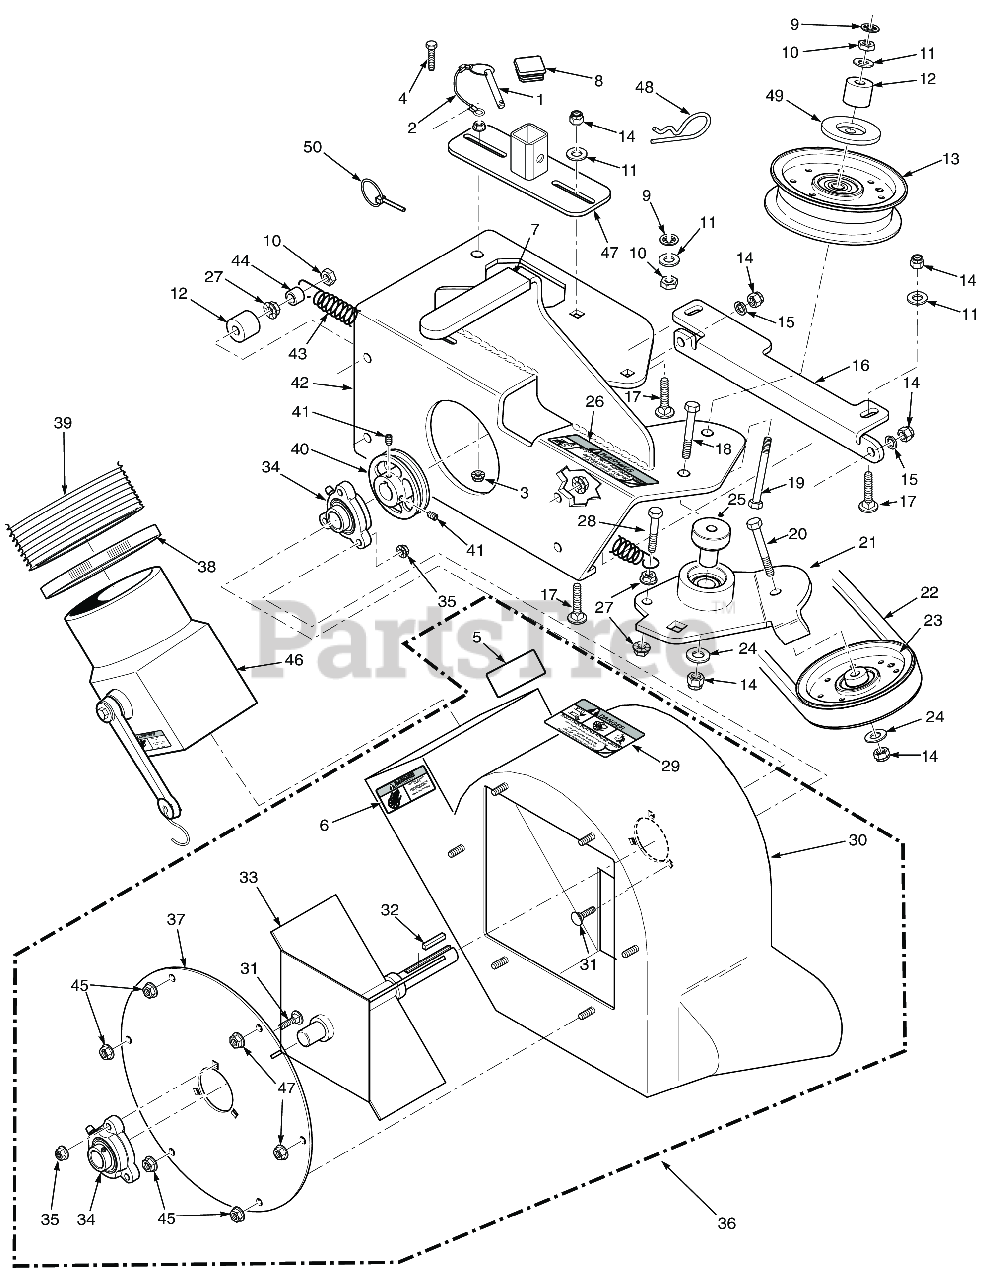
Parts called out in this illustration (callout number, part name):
1	Pin, Ring 1/2 x 2-1/4"
2	Lanyard, Deck Height Pin
3	NUT, 1/4-20 SERRATED FLANGE HEX HEAD
4	SERR. FLG. HEX HEAD CAPSCREW, 5/16-18 X 3/4
5	Decal, Blower
6	Decal, Rotating Blower
7	Grip, Deck Latch Lever
8	Cap, Square Vinyl
9	Nut, Push-On - 3/8" Dia.
10	Bolt, Hex Head 3/8-16 x 1" Ser. Flg.
11	Flatwasher, 3/8" Special (.391 x .938 x .105)
12	SPACER, J-PULL ROD
13	Pulley, Idler 3-1/2" Dia. - 52"
14	HEX NUT, ELASTIC STOP LOCK, 3/8-16
15	Lockwasher, 3/8" Spring, Kawasaki FX / FS
16	Plate, Catcher Mounting
17	Bolt, RDHD Carr. 3/8-16 x 1-1/2 (52" & 61")
18	Bolt, Hex Head 3/8-16 x 3" - 52"
19	Bolt, Hex Head 3/8-16 x 3-1/2" Full Thread
20	Bolt, Hex Head 3/8-16 x 1-3/4" (Kohler EFI)
21	Idler Arm Assembly - 52"
22	Belt, GC-SCZ-48V / STCII-48V
23	Pulley, 3-1/2" O.D., GC-STT 52"
24	Flatwasher, 3/8 (.391 x .938 x .105 HD) Grade 8
25	Pivot, Idler Long - 52"
26	Decal, Warning - Belt Cover
27	NUT, 3/8-16 SERRATED FLANGE HEX HEAD
28	Bolt, Hex Head 3/8-16 x 1-1/2" Grade 8 Black
29	Decal, Danger
30	Blower Housing Weldment w/Decals
31	Bolt, 5/16-18 x .75 RHSN Carriage
32	KEY 1/4 X 1/4 X 1 1/2"(FOR 1" CRANKSHAFT
33	Fan Weldment
34	Bearing Assembly
35	HEX NUT, ELASTIC STOP LOCK, 5/16-18
36	Blower Housing Assembly, GC-STT
37	COVER, BLOWER HOUSING
38	Clamp, 8-5/8" Max Dia. (61")
39	Hose, 8.00" Dia. x 68" Long
40	Pulley, 4-3/4" O.D. - 1" Bore
41	Setscrew, Hex Socket Knurl Cup Pt. 5/16 - 18 (nylock)
42	Frame, Blower Mount
43	Spring, Helper (61" Cutter Deck Only)
44	Spacer, Deck Assist
45	Nut, Serrated Flange 5/16-18 (Right Front Engine Mounting, Briggs and Kohler Only)
46	Adapter, Blower GC-STC,
47	Receiver Weldment, Mount Post - 52"
48	Hair Pin Cotter, .177" x 3-1/4"
49	Quick Pin, 5/16" Dia.
50	Quick Pin, 5/16" Dia.
